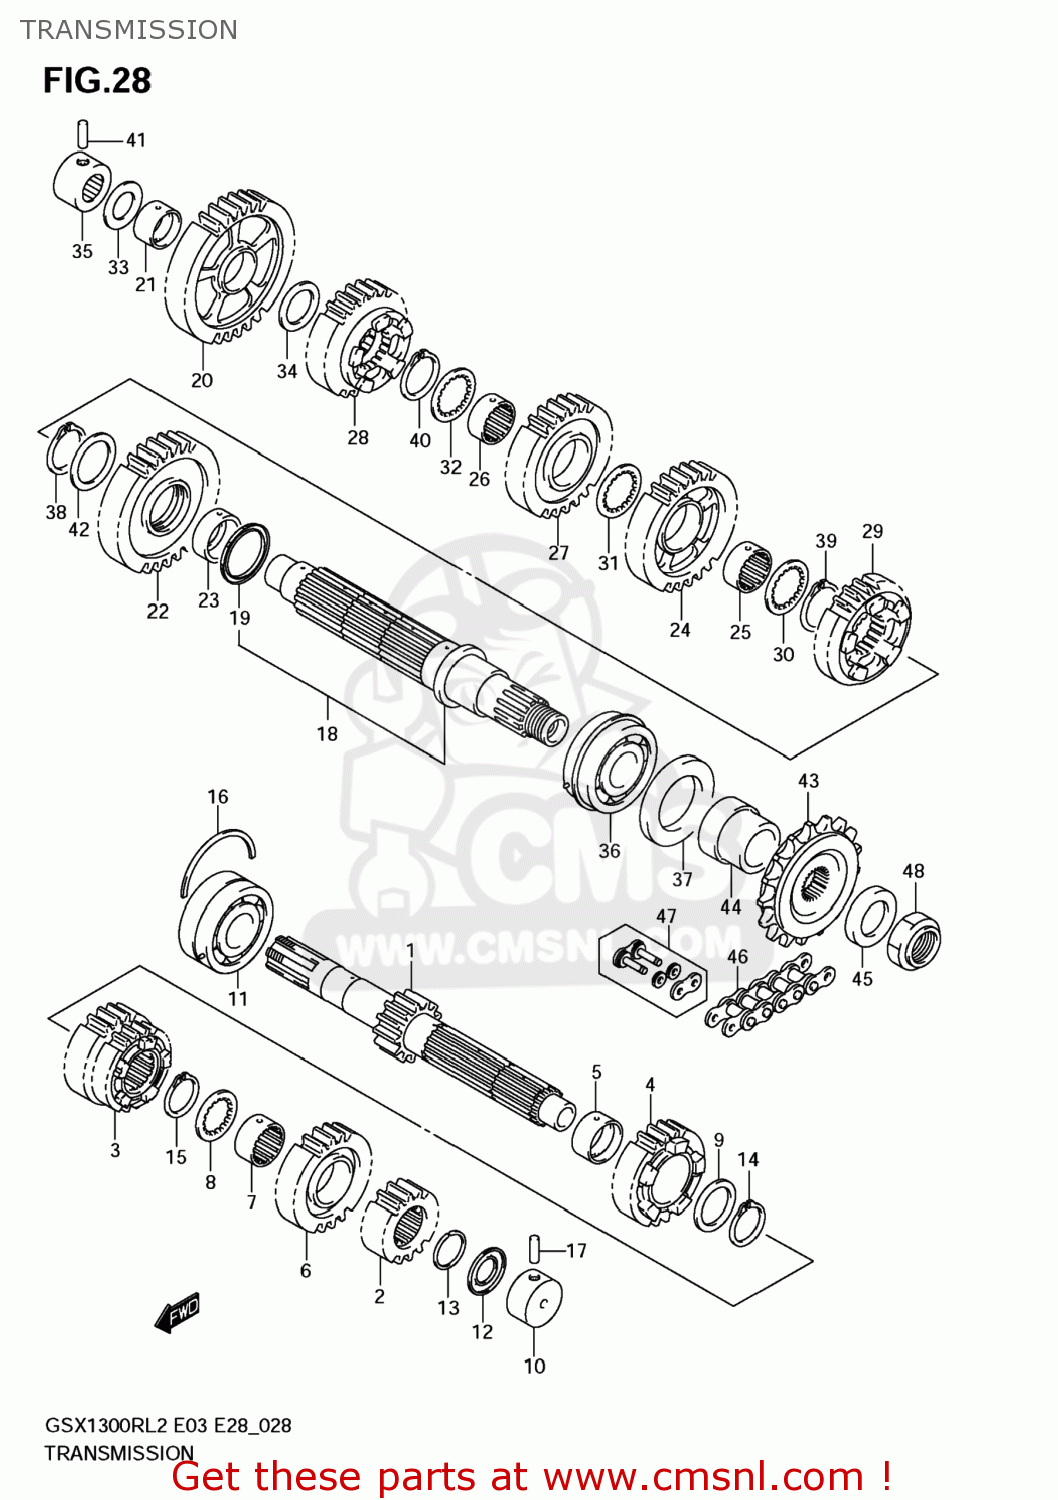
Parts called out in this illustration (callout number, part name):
1	SHAFT,COUNTER
2	GEAR,2ND DRIVE
3	GEAR,3RD & 4TH DRIVE
4	GEAR,5TH DRIVE
5	BUSH,5TH DRIVE GEAR
6	GEAR,6TH DRIVE
7	BUSH,6TH DRIVE GEAR
8	WASHER,LOCK
9	SHIM(27X36X2.5)
10	BEARING(20X34X17.5)
11	BEARING(25X62X25.4)
12	SEAL,OIL(20X31.2X2.7)
13	CIRCLIP
14	CIRCLIP
15	CIRCLIP
16	C RING
17	PIN
18	SHAFT,DRIVE
19	RING,DRIVE SHAFT FRICTION
20	GEAR,1ST DRIVEN
21	BUSH,1ST DRIVEN GEAR
22	GEAR,2ND DRIVEN
23	BUSH,2ND DRIVEN GEAR
24	GEAR,3RD DRIVEN
25	BUSH,DRIVEN GEAR
26	BUSH,DRIVEN GEAR
27	GEAR,4TH DRIVEN
28	GEAR,5TH DRIVEN
29	GEAR,6TH DRIVEN
30	WASHER,LOCK
31	WASHER,LOCK
32	WASHER,LOCK
33	SHIM(20X34X1)
34	SHIM(24X34X1)
35	BEARING(20X34X20)
36	BEARING(30X62X23.8)
37	SEAL,OIL(42X62X7)
38	CIRCLIP
39	CIRCLIP
40	CIRCLIP
41	PIN
42	WASHER
43	SPROCKET,ENGINE(18T)
44	SPACER,ENGINE SPROCKET NO.1
45	SPACER,ENGINE SPROCKET NO.2
46	CHAIN,DRIVE
47	JOINT SET,CHAIN
48	NUT
